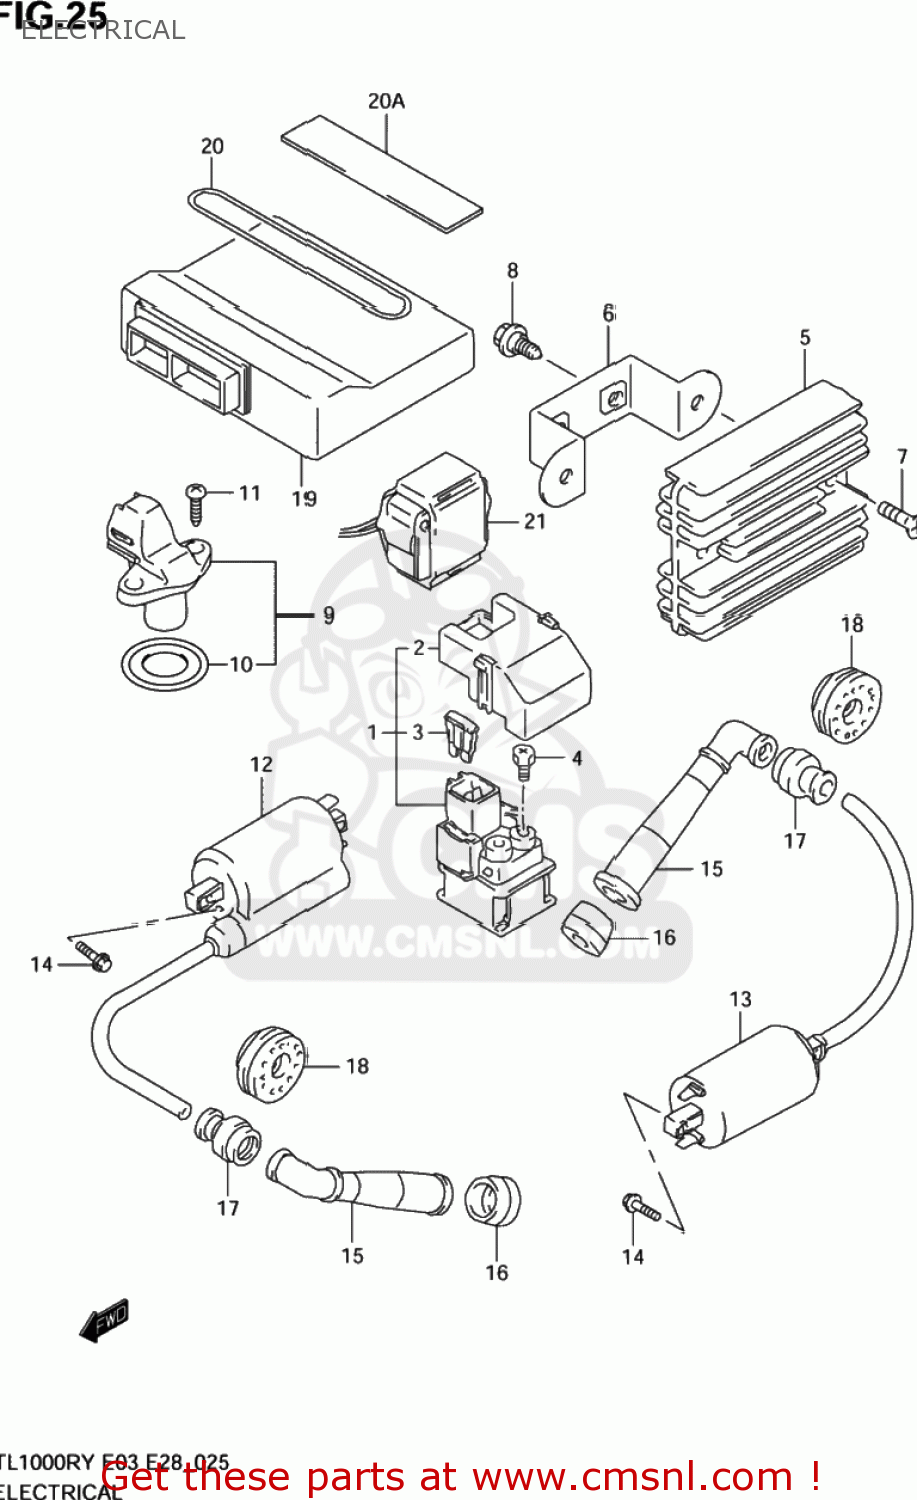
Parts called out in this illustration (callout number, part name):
1	RELAY ASSY,STARTING MOTOR
2	COVER,RELAY ASSEMBLY
3	FUSE(30A)
4	SCREW(6X8)
5	RECTIFIER ASSY
6	BRACKET,RECT FTG
7	BOLT
8	BOLT(6X16)
9	SENSOR ASSY,CAM POSITION
10	PACKING (NAS)
11	SCREW 6X16
12	COIL ASSY,IGNITION
13	COIL ASSY,IGNITION
14	SCREW, PRESSURE SENSOR
15	CAP,SPARK PLUG
16	SEAL,SPARK PLUG CAP
17	SEAL,HIGH TENSION CORD
18	COVER,SPARK PLUG CAP
19	CONTROL UNIT,FI
20	BAND,BATTERY
20A	PROTECTOR(80X80X2)
21	SENSOR ASSY,FUEL CUT
